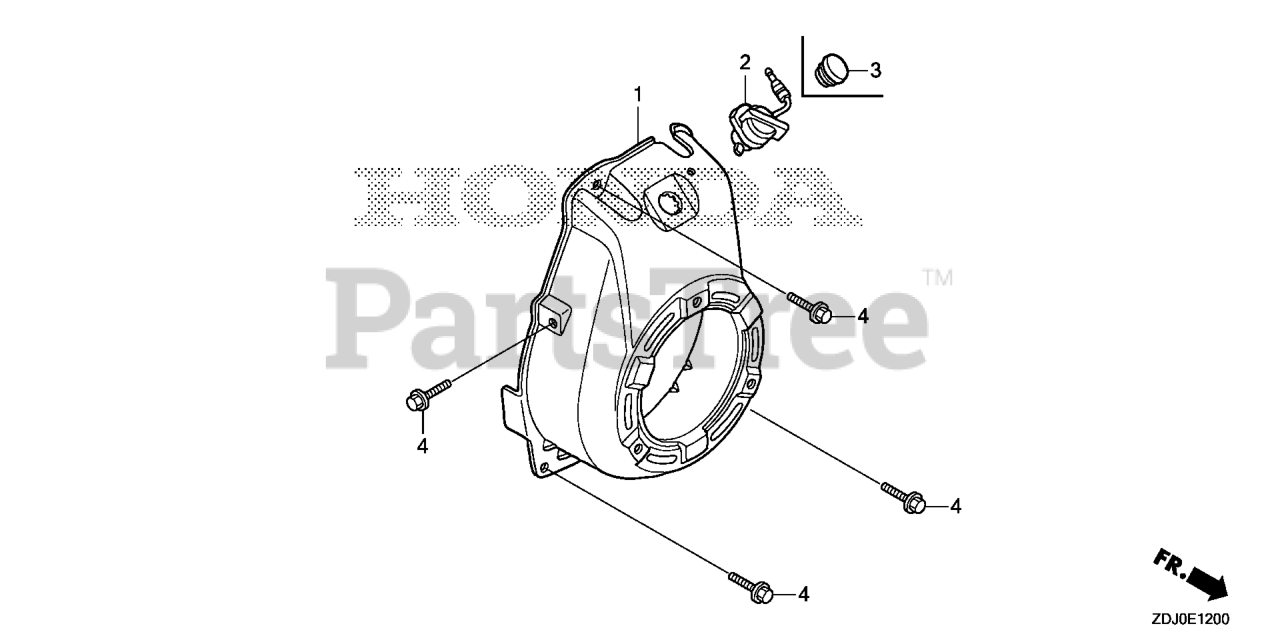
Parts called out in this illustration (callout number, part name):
1	COVER, FAN *NH1* (BLACK)
1	COVER, FAN *R280*
4	BOLT, FLANGE (6X14)
